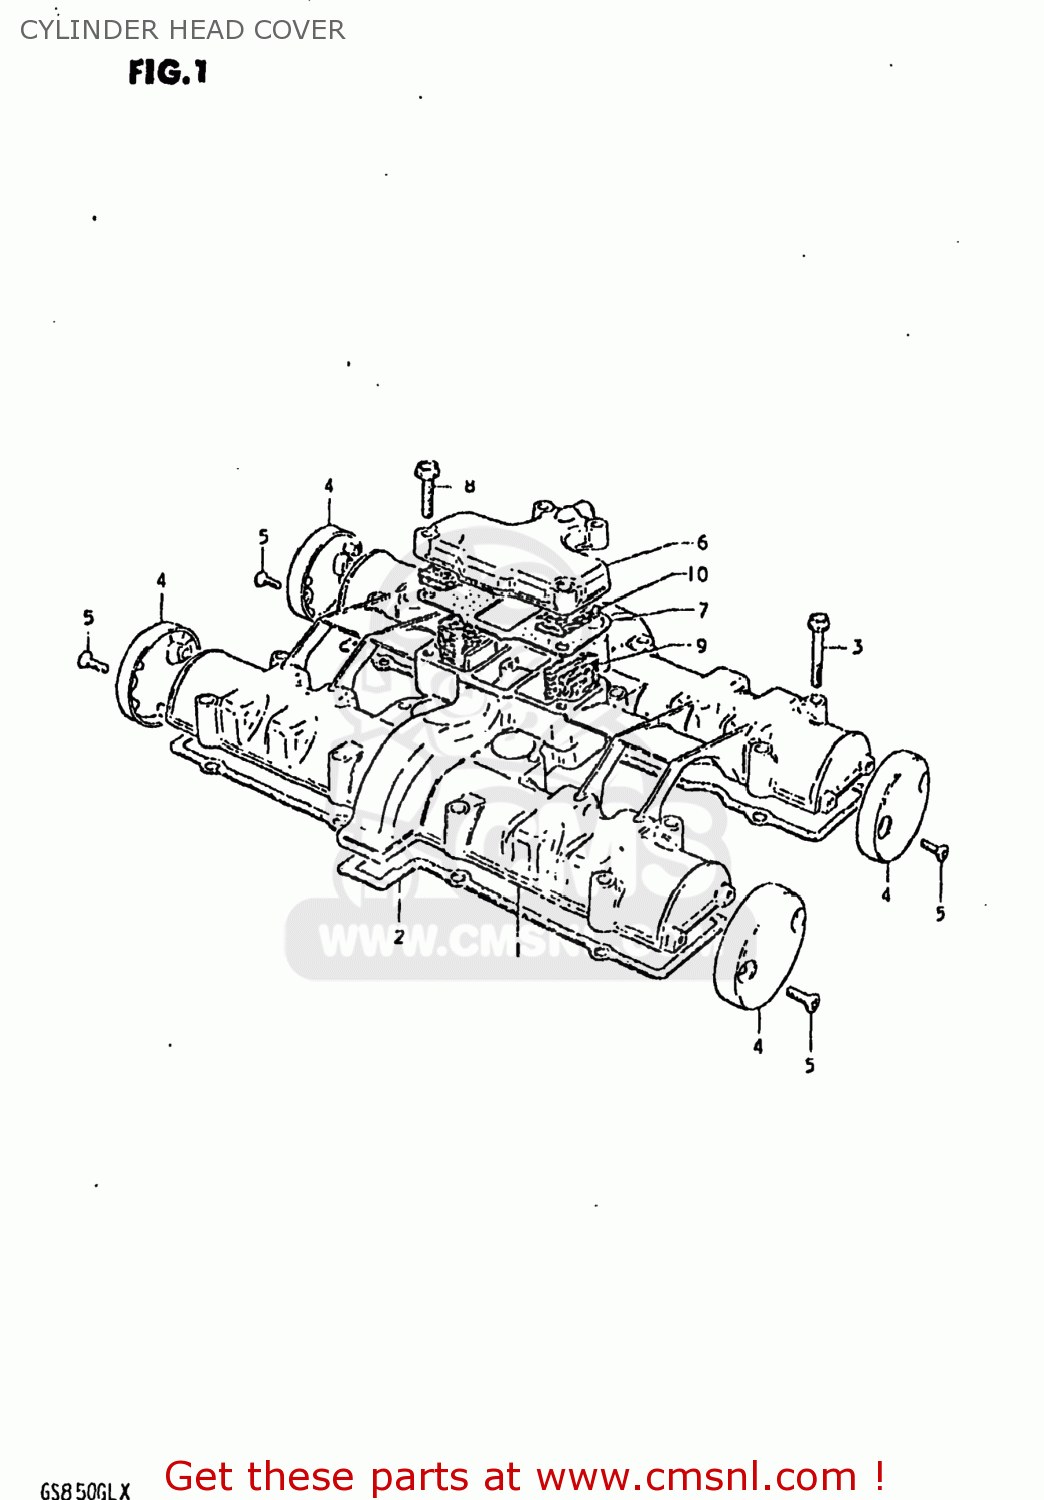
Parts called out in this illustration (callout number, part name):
1	COVER,CYLINDER HEAD
2	GASKET,CYLINDER HEAD COVER (MCA)
3	BOLT
4	CAP,CYLINDER HEAD COVER
5	SCREW 5X12
6	COVER,BREATHER
7	GASKET (MCA)
8	BOLT
9	COVER,BREATHER
10	SEPARATOR,OIL BREATHER
